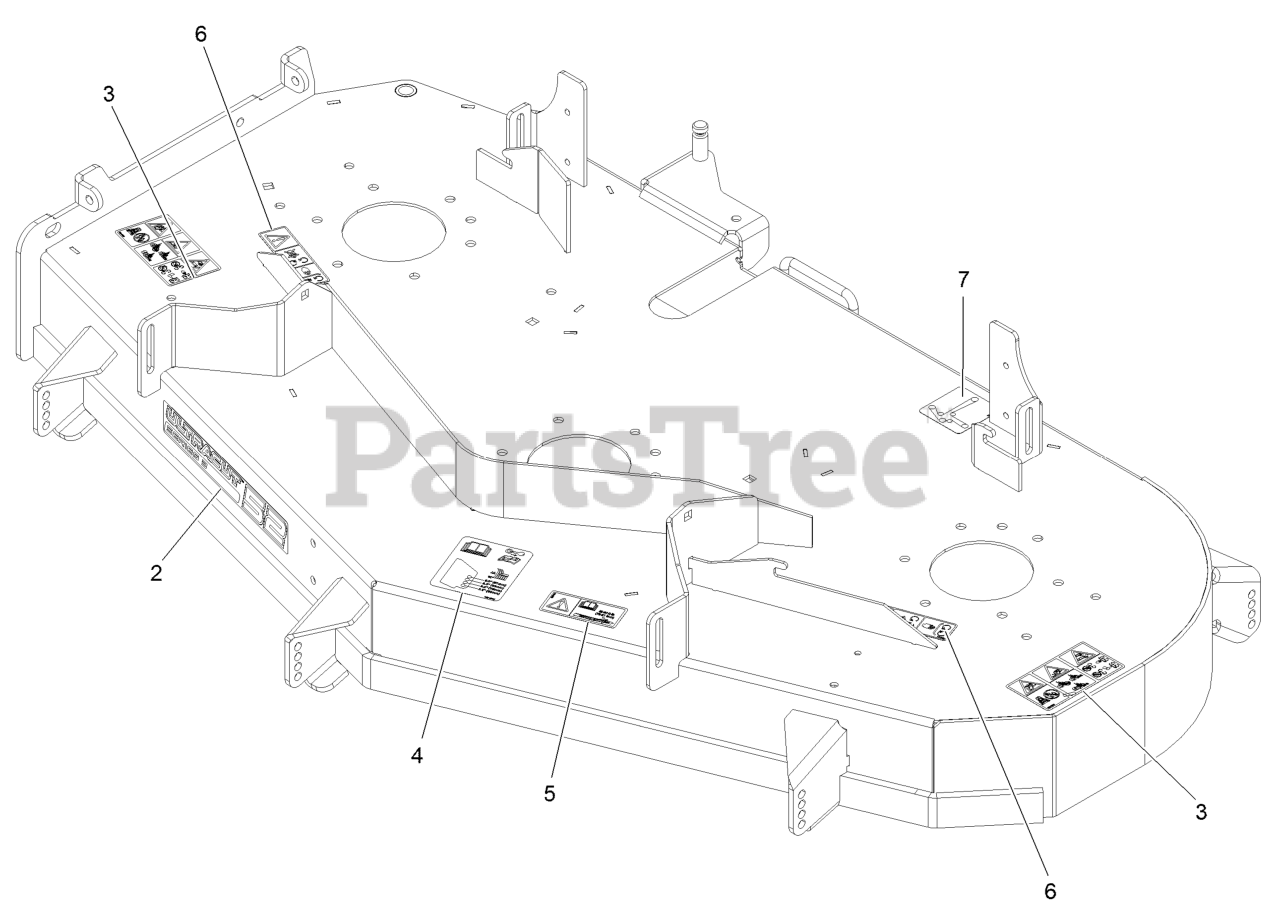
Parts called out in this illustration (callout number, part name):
2	DECAL-ULTRACUT 52 SERIES
3	DECAL-DANGER THROWN OBJECTS
4	DECAL-ROLLER, ANTI-SCALP
5	DECAL-BOLT TORQUE
6	DECAL-COVER, MISSING
7	DECAL-ROUTING, BELT
